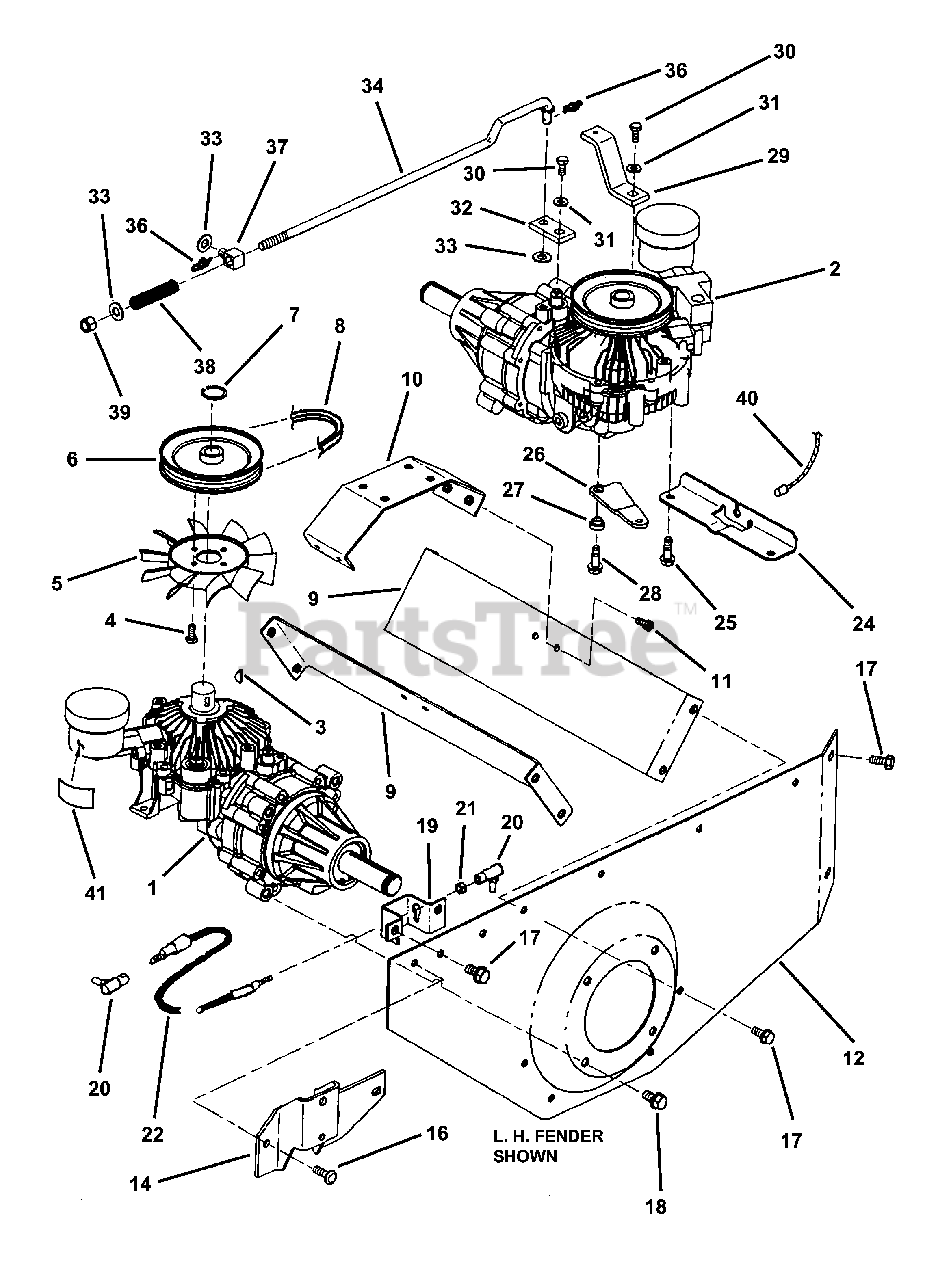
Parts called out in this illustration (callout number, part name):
1	TRANSAXLE, Hydro L.H. (Eaton Model X778-005)
2	TRANSAXLE, Hydro w/o Manifold R.H. (Eaton Model X778-011)
3	KEY, #605 Woodruff
4	SCREW, 1/4-20 x 1/2" Self-Tapping
5	FAN, 6" O.D., 10 Blade
6	PULLEY, Hydro Input
7	RING, Retaining
8	V-BELT, Hydro Drive
9	BRACKET, Fender Support
10	BRACKET, Hydro Support
11	SCREW, 1/4-20 Hex Washer Head, Self-Tapping
12	FENDER, L.H,
14	BRACKET, Deck Support L.H.
16	SCREW, 5/16-18 x 7/8" Pan Head, Self-Tapping
17	SCREW, 5/16-18 x 3/4" Hex Washer Head, Self-Tapping
18	SCREW, 3/8-16 x 3/4" Hex Washer Head, Self-Tapping
19	BRACKET, Hydro Control Cable
20	ROD END, #10-32 w/Stud
21	NUT, #10-32 Hex Center Lock
22	CABLE, L.H. Hydraulic Control (45.5" long)
24	BRACKET, Hydro Release Cable
25	SCREW, 5/16-18 x 5/8" Hex Washer Head, Self-Tapping
26	BRACKET, Hydro Release Actuator
27	BUSHING,
28	SCREW, 5/16-18 x 1" Hex Washer Head, Self-Tapping
29	ARM, Brake
30	BOLT, 1/4-28 x 5/8" Hex Head, Grade 8
31	WASHER, 1/4 Belleville
32	ARM, Brake
33	WASHER, 3/8" Flat
34	ROD, R.H. Brake
36	COTTER-PIN, 1/16" x 1.42" Self-Locking
37	LINK, Swivel Brake
38	SPRING, Brake Compression
39	NUT, 3/8-16 Nyloc
40	CABLE, Hydro Release Valve
41	DECAL, Hydro Reservoir
